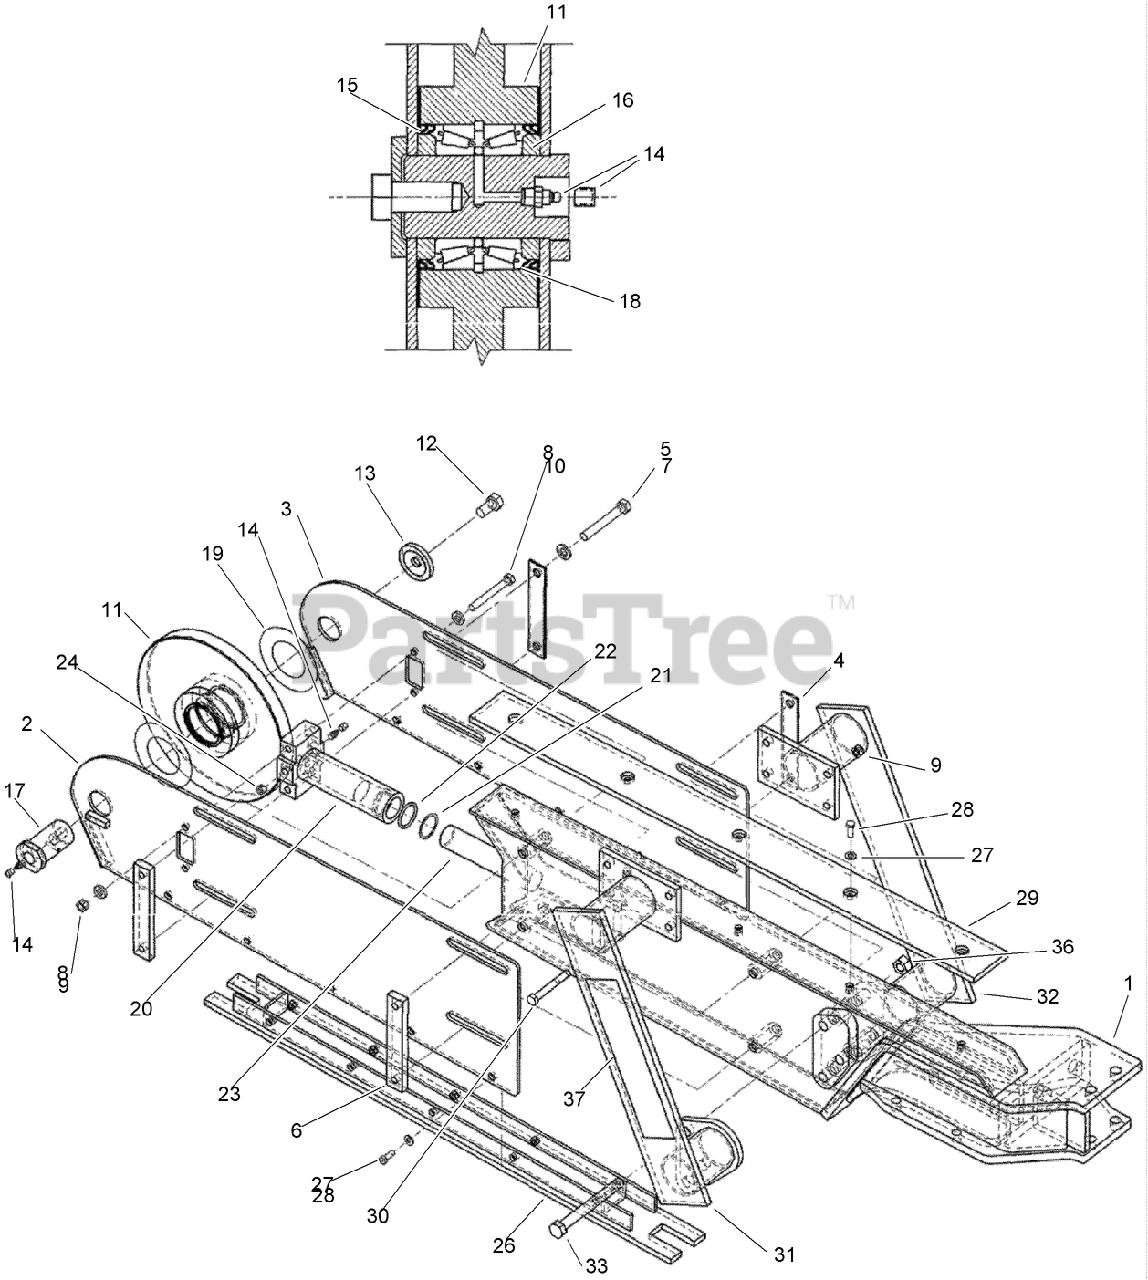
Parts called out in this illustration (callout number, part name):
1	BOOM-trencher, 4 foot, rock
2	PLATE-Boom End (RH)
3	PLATE-Boom End (LH)
4	BAR-Clamp
5	WASHER-LOCK
6	BAR-Tapped
9	NUT-HEX
10	BOLT-hex, 1/2 NC x 4-1/4 inch
11	BOLLER-Boom End
14	FITTING-LUBE, STRAIGHT
15	SEAL-ROLLER
16	SPACER-bearing
17	PIN-BOOM
18	BEARING KIT
19	WASHER-BOOM, END (ROLLER)
20	CYLINDER-Boom End
21	WASHER-BACKUP
22	O-RING
23	ROD-BOOM, END (CYLINDER)
24	PLUG-BLEED
26	CHANNEL-wear pad, lower
27	WASHER-3/8 HT
28	SCREW-HH
29	BAR-Wear Pad, Upper, 4\ Boom
30	SCREW-HH
31	MOUNT-Crumber RH
32	MOUNT-Crumber LH
36	NUT-Prev Trq 3/4 GRC CAD Direct
37	DECAL-Danger, Trencher Entanglement Hazard
